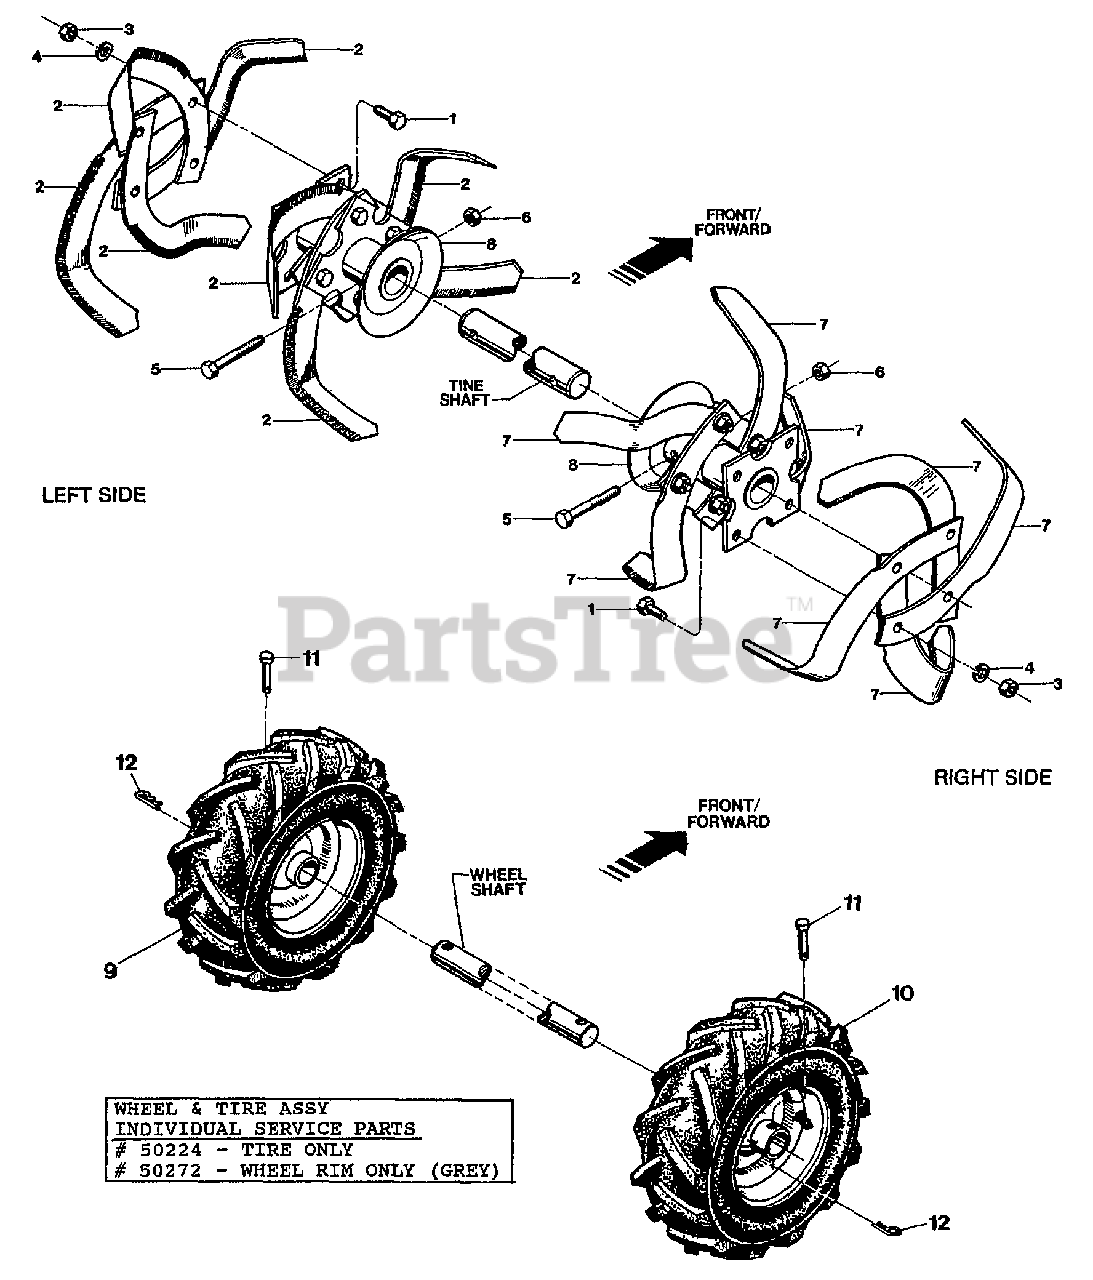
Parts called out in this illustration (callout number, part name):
1	SCR-HH 3/8-16X1.0 G5 ZP
2	TINE-BOLO RH TINE USED ON LEFT SIDE OF TILLER.
3	NUT-HEX 3/8-16 ZP
4	WASHER-LK .375 @ DEPL
5	SCR-HH 3/8-16X2.00 G8
6	NUT-H/LK 3/8-16
7	TINE-BOLO LH TINE USED ON RIGHT SIDE OF TILLER.
8	HOLDER-TINE JUNIOR (FOR BOLO TINES, LH & RH SIDES.)
9	ASSM-WHEEL&TIRE LT
10	ASSM-WHEEL&TIRE RT
11	PIN-CLEVIS .312"X11/2" (SECURES WHEEL HUB TO WHEEL SHAFT)
12	PIN-CLIP .08
